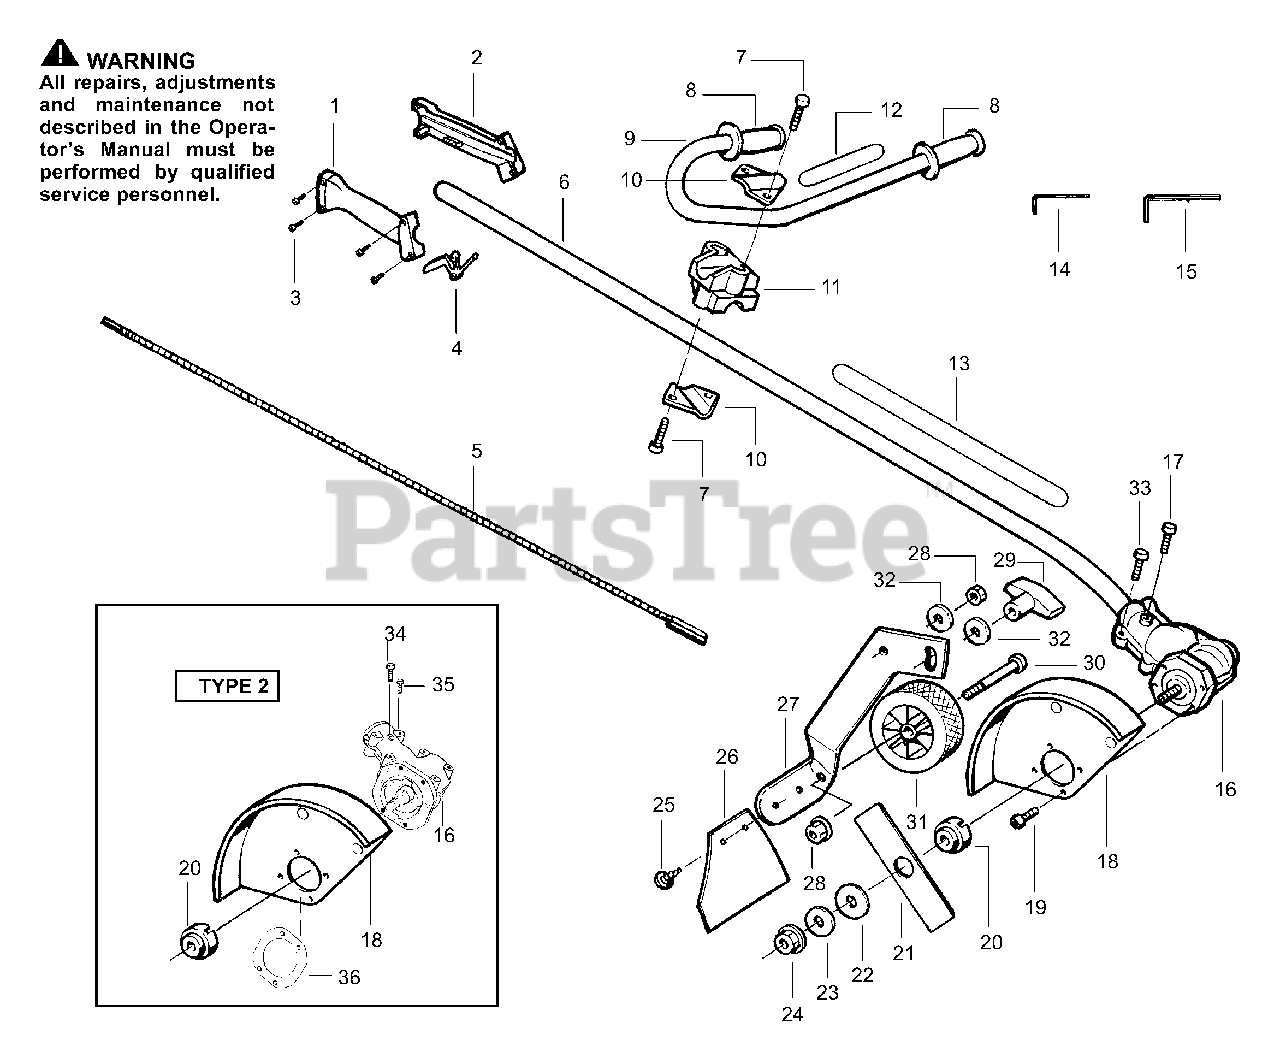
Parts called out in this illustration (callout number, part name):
1	Throttle Hsg. Right
2	Throttle Hsg. Left
4	Lever-Throttle
5	Shaft-Flex
6	Assy-Driveshaft
8	Fin Grip
9	Assy-Handlebar
10	Bracket-Handlebar
11	Clamp-Handlebar
12	Decal-Handlebar
13	Decal-Shaft Warning
14	Hex Wrench (5/32)
15	Hex Wrench (3/16)
16	Assy-Gearbox
18	Guard
18	Type 2
20	Kit-Dust Cup
22	Washer-Flat
23	Washer-Belleville
24	Nut-Flange
25	Fastener Mud Flap
26	Mud Flap Kit
27	Wheel Bracket
30	Bolt-Shoulder Axle
31	Wheel (Front)
36	Plate
